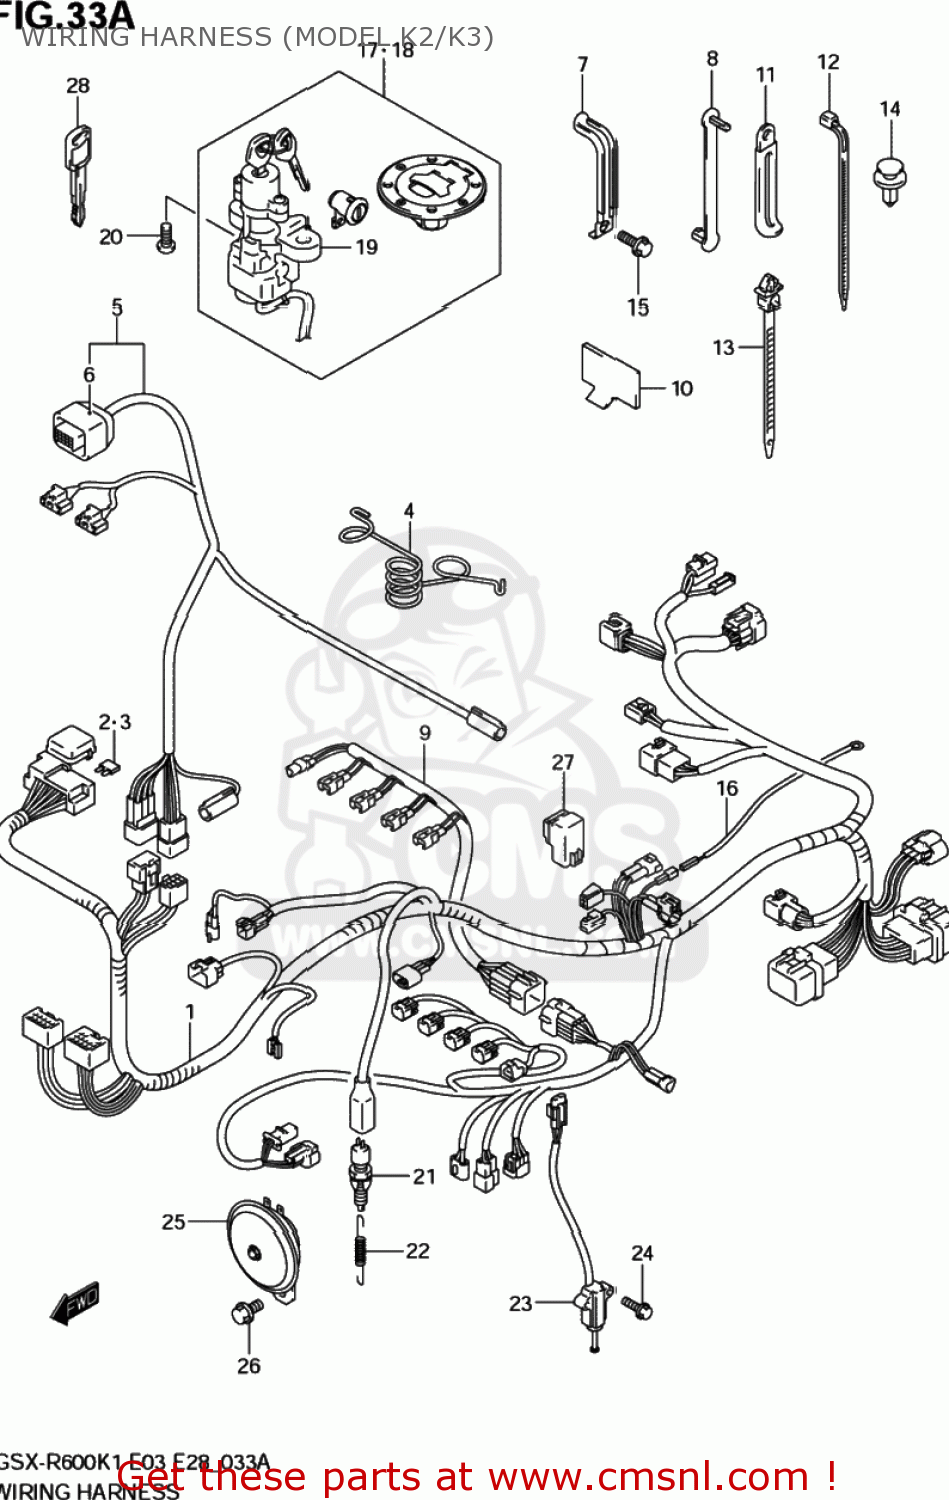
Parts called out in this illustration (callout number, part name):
1	HARNESS,WIRING NO.1
2	FUSE(10A)
3	FUSE(15A)
4	GUIDE,WIRING HARNESS
5	HARNESS,WIRING NO.2
6	COVER,SPEEDOMETER COUPLER
7	CLAMP
8	CLAMP(L:63)
9	WIRE,INJECTOR LEAD
10	PROTECTOR,WIRING HARNESS
11	CLAMP(L:65)
12	CLAMP(L:235)
13	CLAMP(L:90)
14	CLAMP(L:120)
15	BOLT
16	WIRE,OIL PRESSURE SWITCH LEAD
17	LOCK SET
18	LOCK SET
19	LOCK ASSY,STEERING
20	BOLT(8X20)
21	SWITCH ASSY,STOP LAMP
22	SPRING
23	SWITCH ASSY,SIDE STAND
24	BOLT
25	HORN ASSY
26	BOLT
27	RELAY ASSY
28	KEY,BLANK
